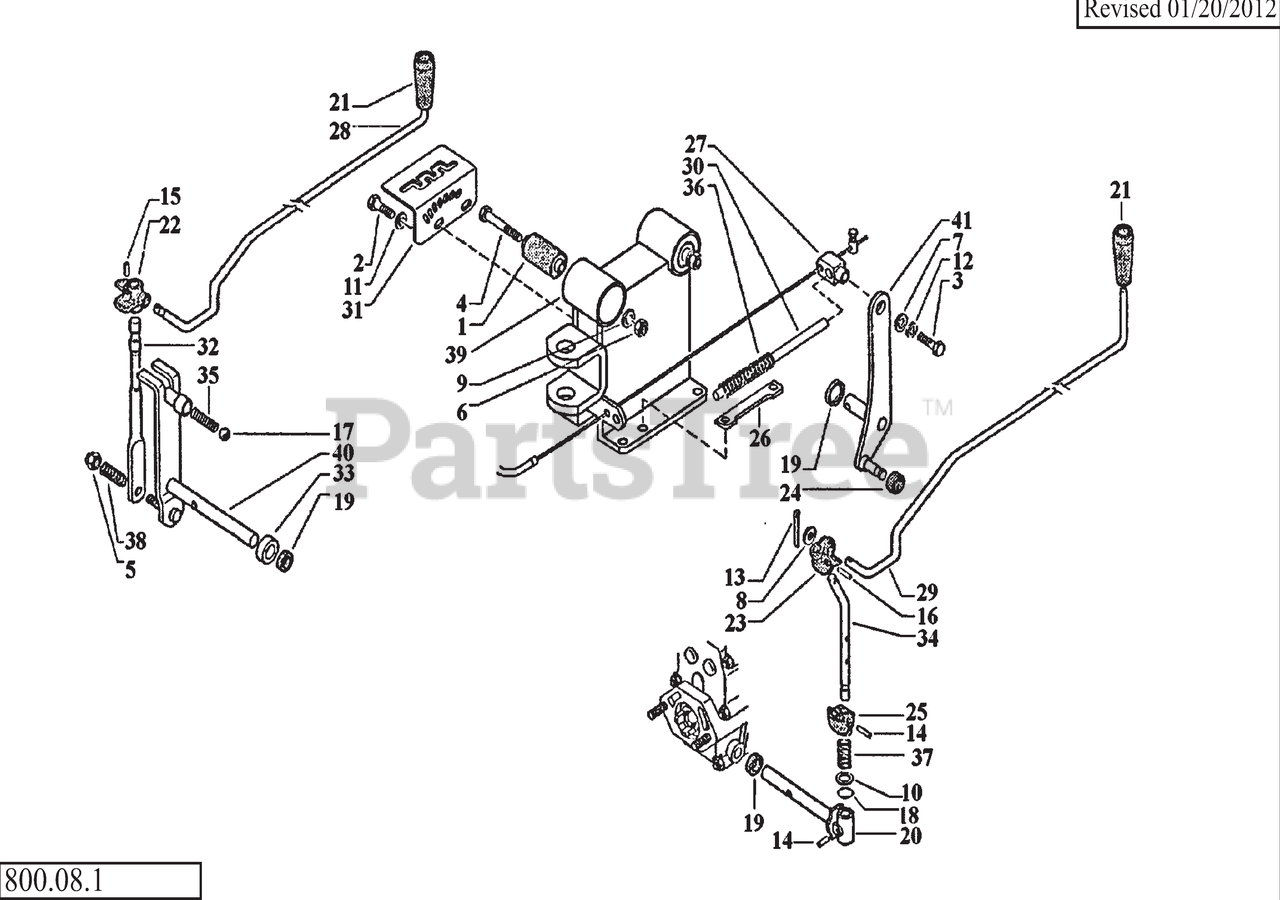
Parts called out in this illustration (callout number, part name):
1	SILENT BLOCK, 12X40X58X66-
2	CAP SCREW, M8X14
3	CAP SCREW, M8X12
4	CAP SCREW, M12X100
5	NUT, SELF LOCKING, M8
6	NUT, SELF LOCKING, M12
7	WASHER, FLAT, M8.4
8	WASHER, FLAT, M10.5
9	WASHER, FLAT, M13X25
10	WASHER, FLAT, M13
11	WASHER, SUPER, M8
12	WASHER, LOCK, M8.4
13	PIN, COTTER, M2X15
14	PIN, SPIROL, M4X20
15	PIN, SPIROL, M3X22
16	PIN, SPIROL, M4X24
17	BALL, 15/32
18	O-RING
19	OIL SEAL, M14X22X4
20	SHAFT, PTO
22	JOINT
23	ARTICULATION, PTO
24	PIN, PTO LOCKOUT
25	ARTICULATION, PTO
26	LEVER, REVERSE SPEED
27	BLOCK, REVERSER
28	CONTROL ROD, GEAR SELECT
29	CONTROL ROD, PTO
30	PIN, GUIDE
31	GEAR QUADRANT
32	LEVER, GEAR
33	SPACER
34	SHIFT ARM, PTO
35	SPRING
36	SPRING, REVERSER
37	SPRING
38	SPRING
39	SUPPORT, STEERING COLUMN
40	LEVER, SPEED SELECTOR
41	LEVER, PTO LOCKOUT
